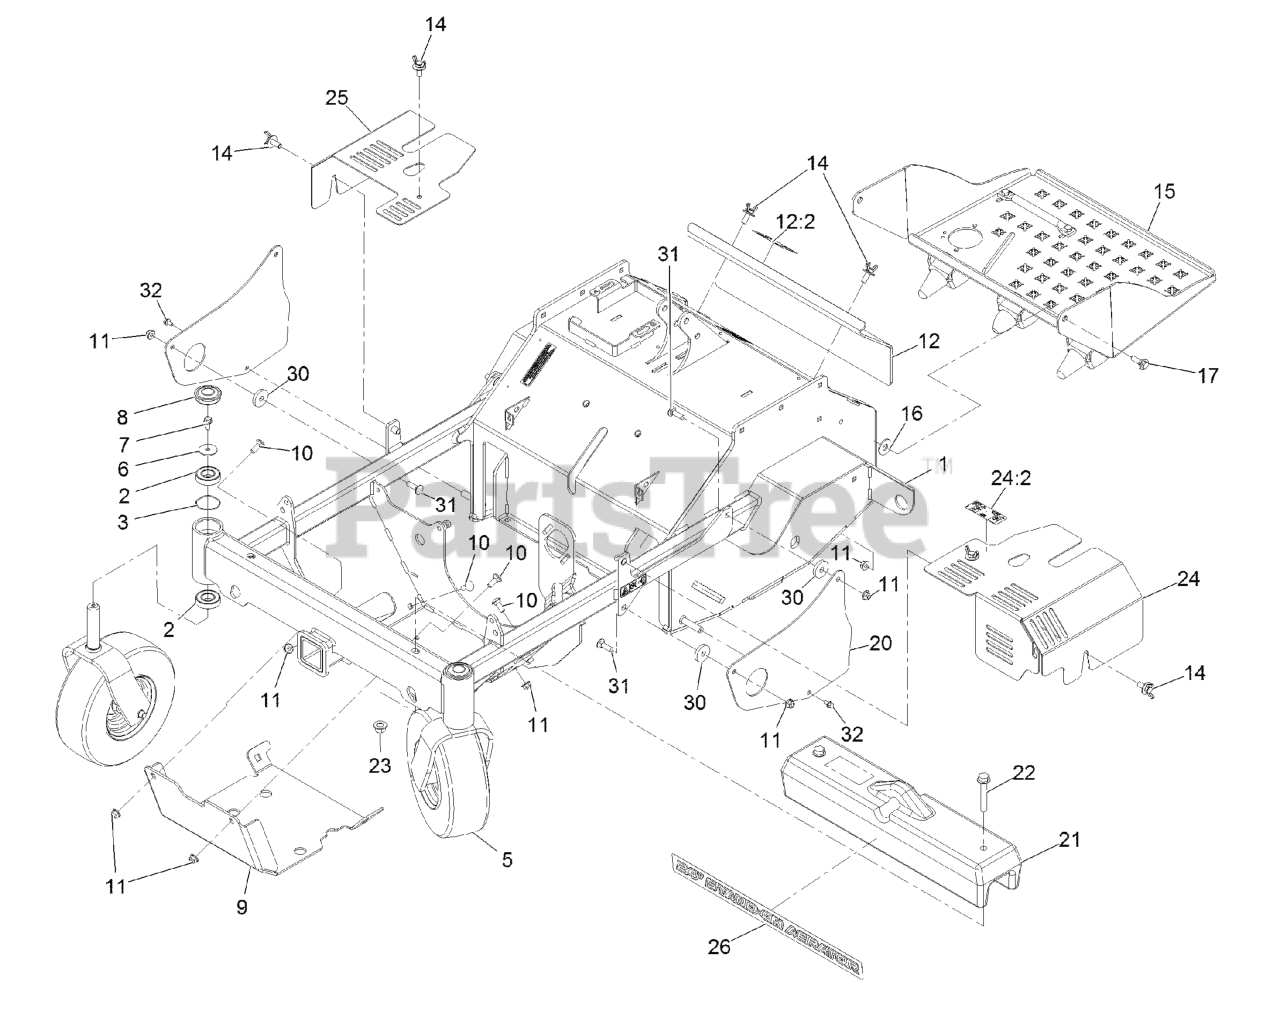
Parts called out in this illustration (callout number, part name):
1	Main Frame ASM
2	BEARING-BALL
5	Front Caster ASM
6	WASHER-FLAT
7	SCREW-HHF
8	CAP-GREASE
9	GUARD-ENGINE
10	BOLT-CARR
11	NUT-HF, NI
12	ACCESS COVER ASM
12:2	DECAL-OPERATION, TINE GRO
14	Screw-Sems (3/8-16 X 1)
15	PLATFORM ASM
16	WASHER-FLAT
17	SCREW-SHOULDER, HWH
20	Guard-Chain
21	WEIGHT-FRONT
22	SCREW-HF
23	Nut-Lock 1/2-13
24	HYDRO-COVER
24:2	DECAL-RELEASE, DRIVE
25	COVER-HYDRO
26	DECAL-STANDON AERATOR 24
30	WASHER-CLUTCH
31	BOLT-CARR
32	SCREW-HHF
